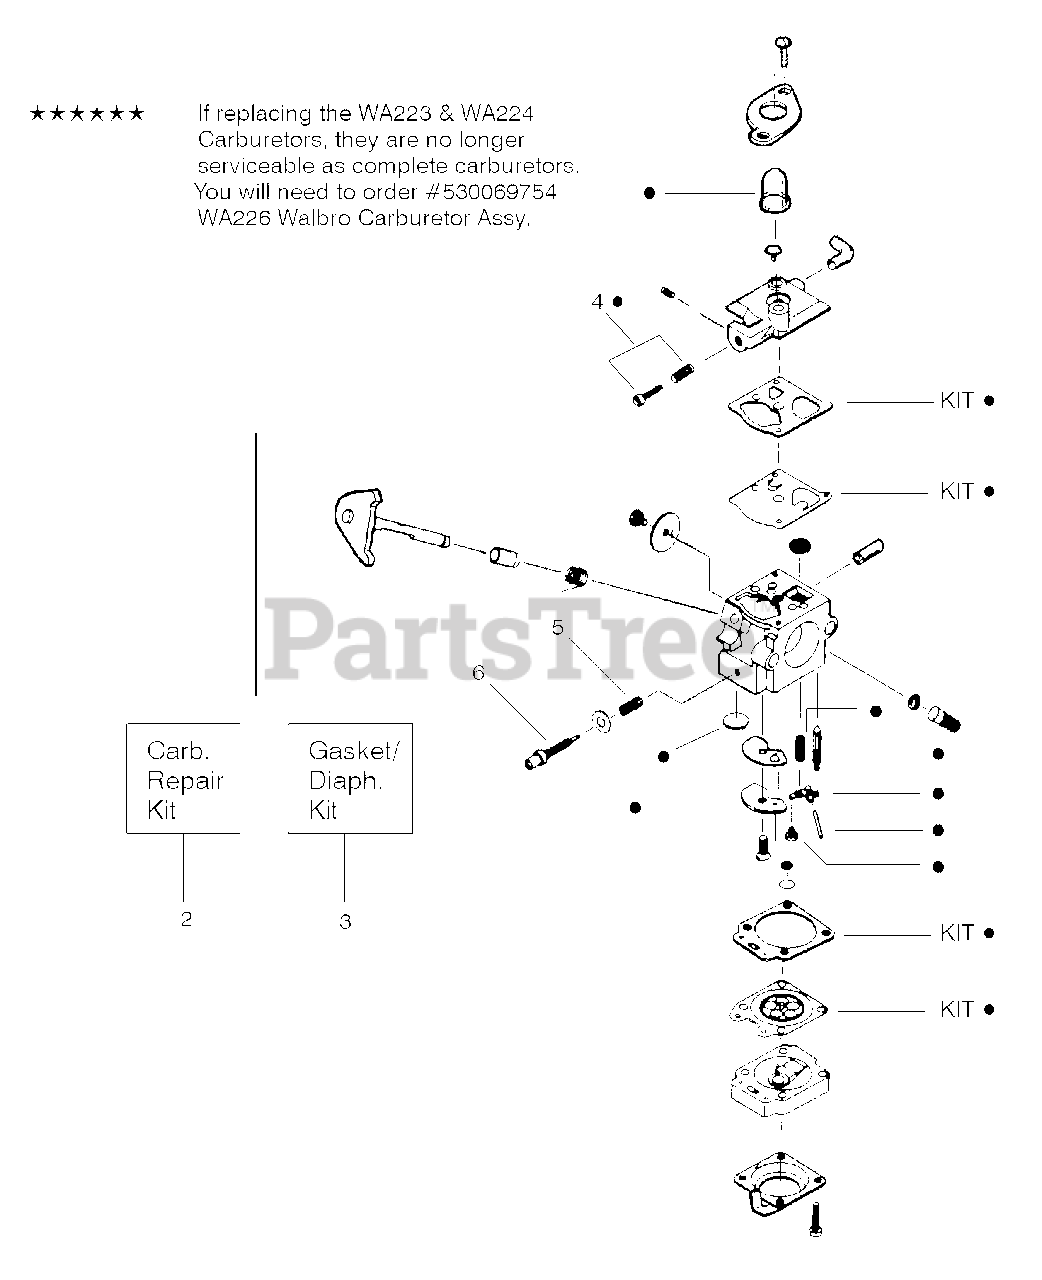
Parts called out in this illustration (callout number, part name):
1	Limiter Cap
2	Carburetor Repair Kit C1U-W7 (Zama)
3	Gasket/Diaphragm Kit C1U-W7 (Zama)
4	Idle Screw & Spring Kit
5	Low Speed Spring
6	Low Speed Needle
530069754	KIT-CARBURETOR ASSY
